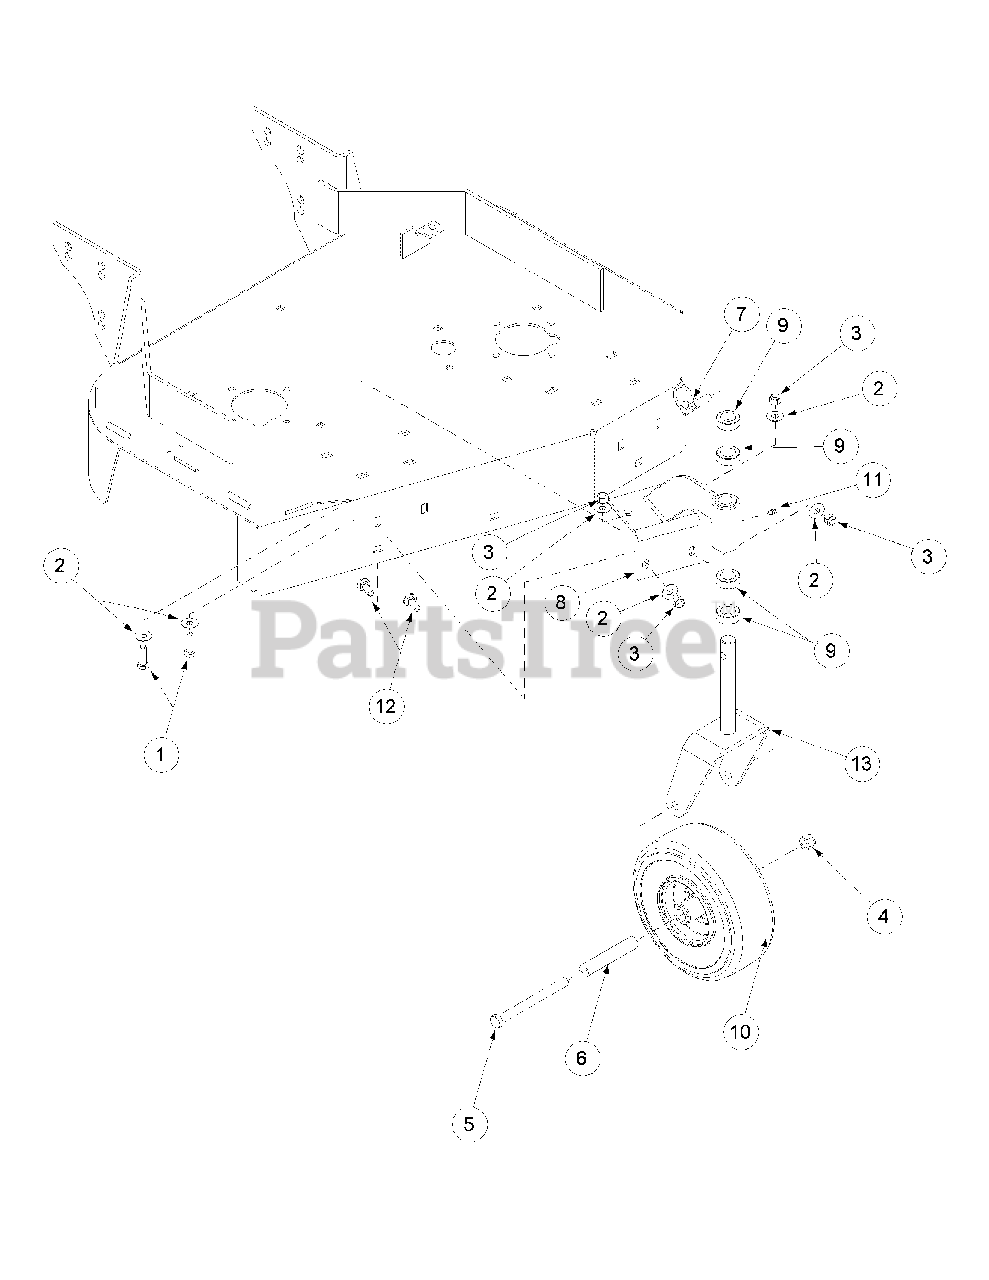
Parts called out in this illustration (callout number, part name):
1	Hex Cap Screw, 3/8-16 x 1-1/4
2	Flat Washer, 3/8 Zinc
3	Lock Nut, Nylon Insert, 3/8-16
4	Lock Nut, Nylon Insert, 1/2-13
5	Hex Cap Screw, 1/2-20, 5.50
6	Spacer Wheel
7	Klik Pin, 1.75
8	Caster Bracket Assembly
9	Spacer, Caster
10	Wheel Assembly, 9.0 x 3.50-4
11	Grease Fitting, 1/4-28 x 3/16
12	Carriage Bolt, 3/8-16 x 1
13	Caster Yoke Assembly, Weldment
